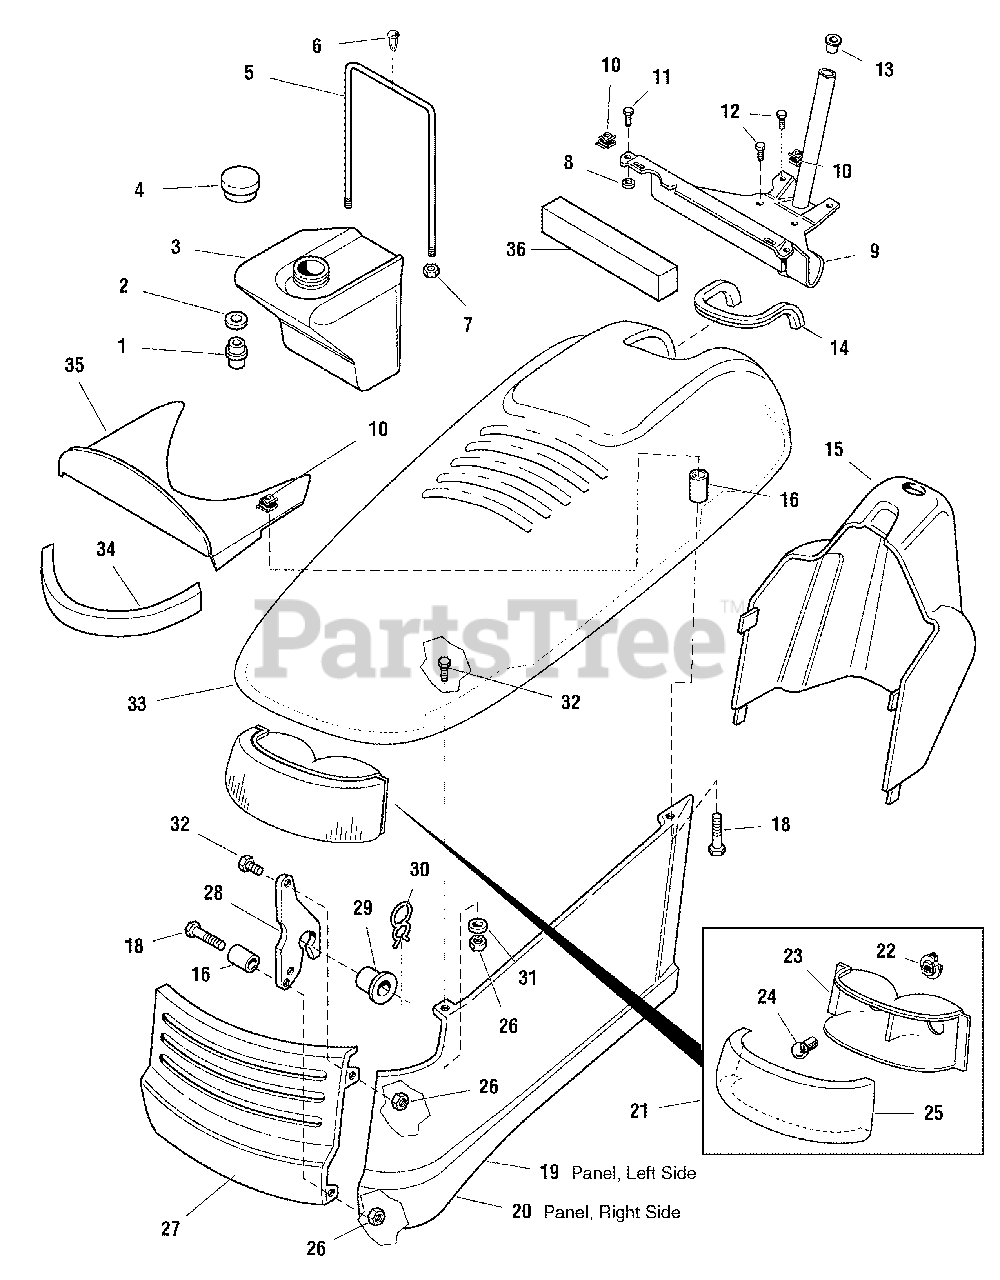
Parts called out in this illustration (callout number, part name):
1	ELBOW, Fuel Tank to Fuel Hose
6	FASTENER, Panel
7	NUT, Hex Lock ESNA light, 5/16-18
8	WASHER
9	BULKHEAD & TUBE ASSEMBLY
10	NUT, Speed
11	SCREW, Hex Washer Head Taptite, 1/4-20 x 1/2
12	SCREW, Hex Washer Head Taptite, 1/4-20 x 1/2
15	DASHBOARD, Honda
18	CAPSCREW, Hex Head, 1/4-20 x 1-1/2
19	PANEL, Hood, LH
19	PANEL, Hood, LH, Red
20	PANEL, Hood, RH, Orange
20	PANEL, Hood, RH, Red
21	HEADLIGHT ASSEMBLY, (Includes Ref. Nos. 22, 23, 24, 25)
22	SOCKET, Headlight
23	BEZEL, Headlight
24	BULB, Headlight, 12.8V
25	LENS, Headlight
26	NUT, Hex Lock ESNA light, 1/4-20
27	GRILLE, Orange
27	GRILLE, Red
28	HINGE
31	WASHER
32	CAPSCREW, Hex Head Flange Lock, 1/4-20 x 5/8
33	HOOD, Orange
33	HOOD, Red
35	DUCT, Cooling
36	SEAL, Foam Block
